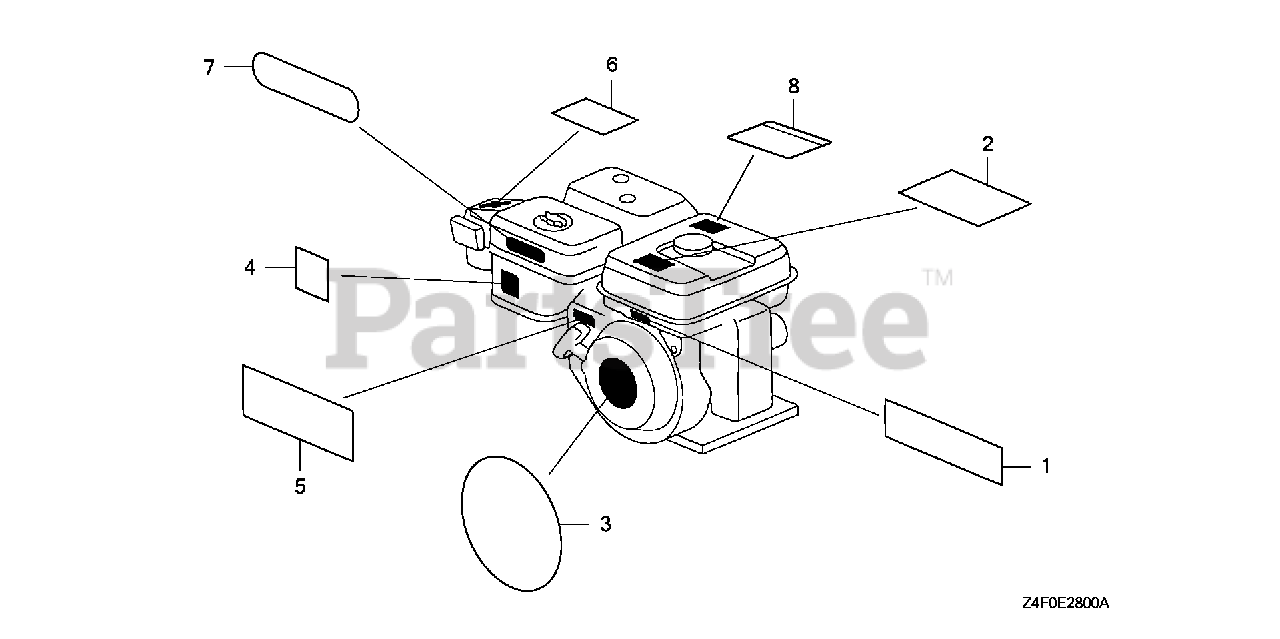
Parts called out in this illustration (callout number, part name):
2	MARK, OPERATOR CAUTION (ENGLISH)(MADE IN JAPAN)
2	MARK, OPERATOR CAUTION (PICTOGRAPH)(MADE IN JAPAN)
3	EMBLEM (GX120)
4	MARK, CHOKE (GRAY)
5	MARK, THROTTLE INDICATION
8	MARK, EX. CAUTION (ENGLISH)
